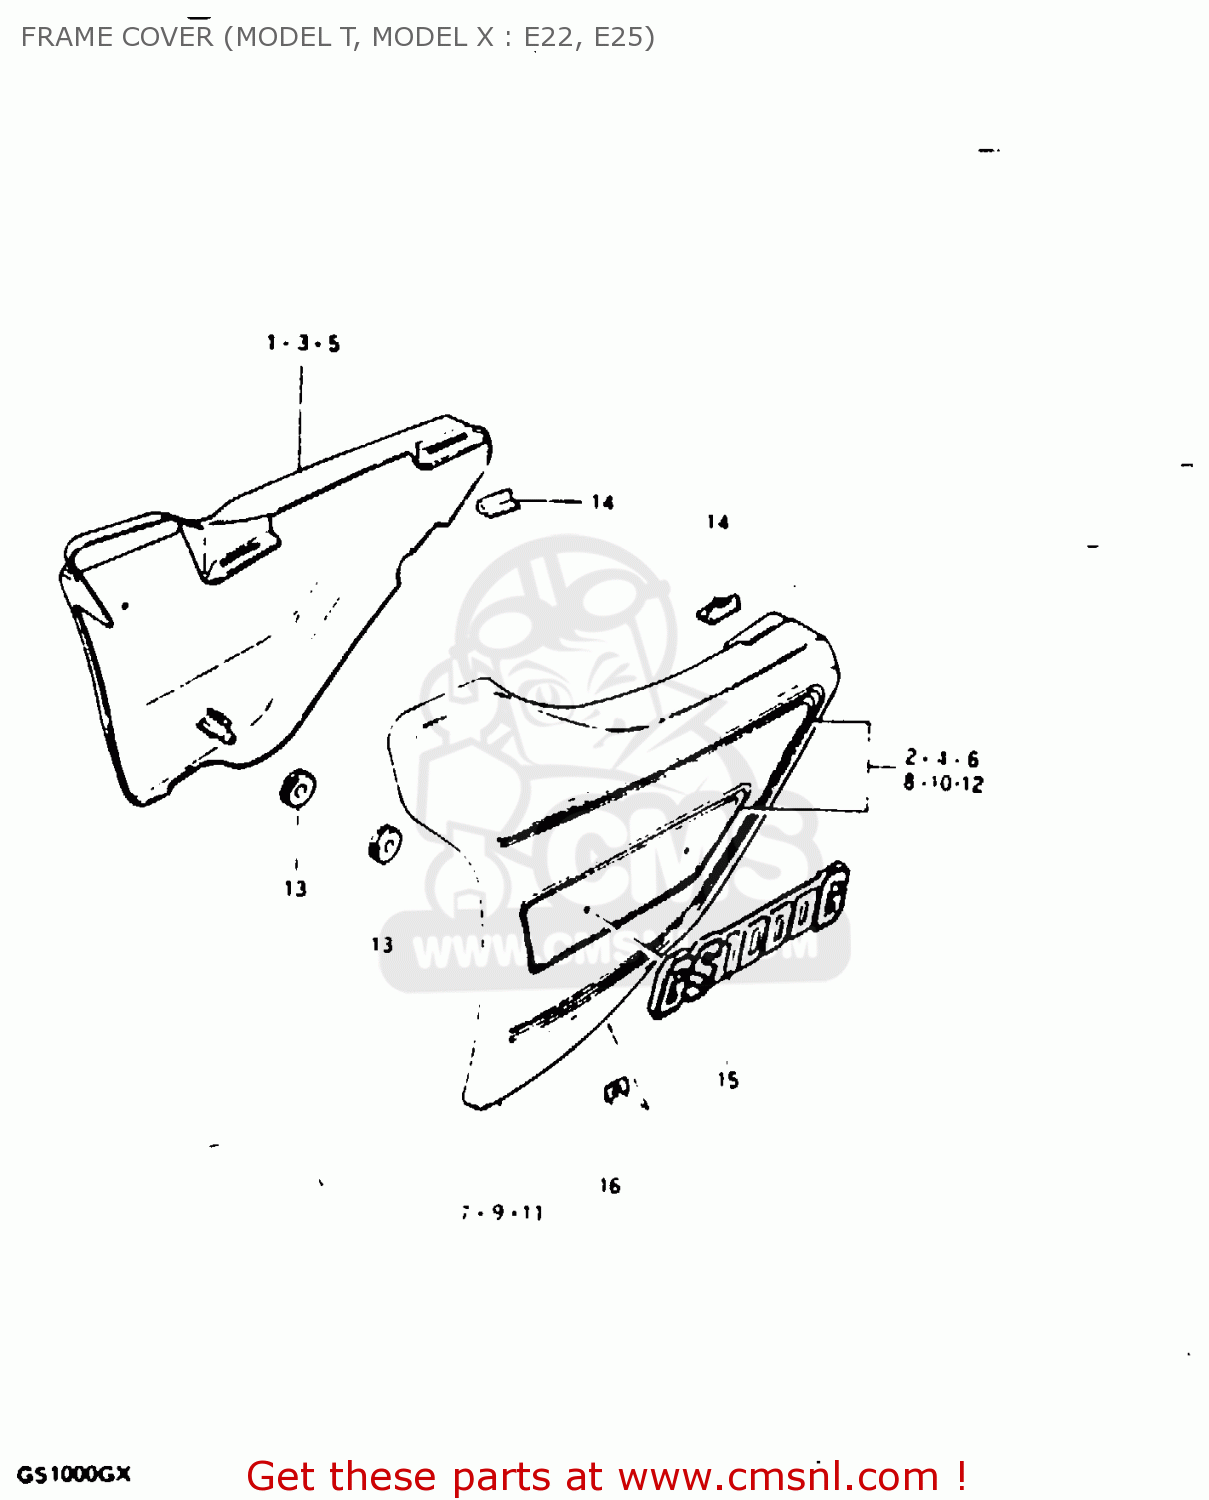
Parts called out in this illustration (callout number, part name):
1	COVER, FRAME RH (BLACK)
2	TAPE SET, RH
3	COVER, FRAME RH (SILVER)
4	TAPE SET, RH
5	COVER, FRAME RH (BLUE)
6	TAPE SET, RH
7	COVER, FRAME LH (BLACK)
8	TAPE SET, LH
9	COVER, FRAME LH (SILVER)
10	TAPE SET, LH
11	COVER, FRAME LH (BLUE)
12	TAPE SET, LH
13	CUSHION
14	CUSHION,FRAME COVER
15	EMBLEM,FRAME COVER
16	NUT
